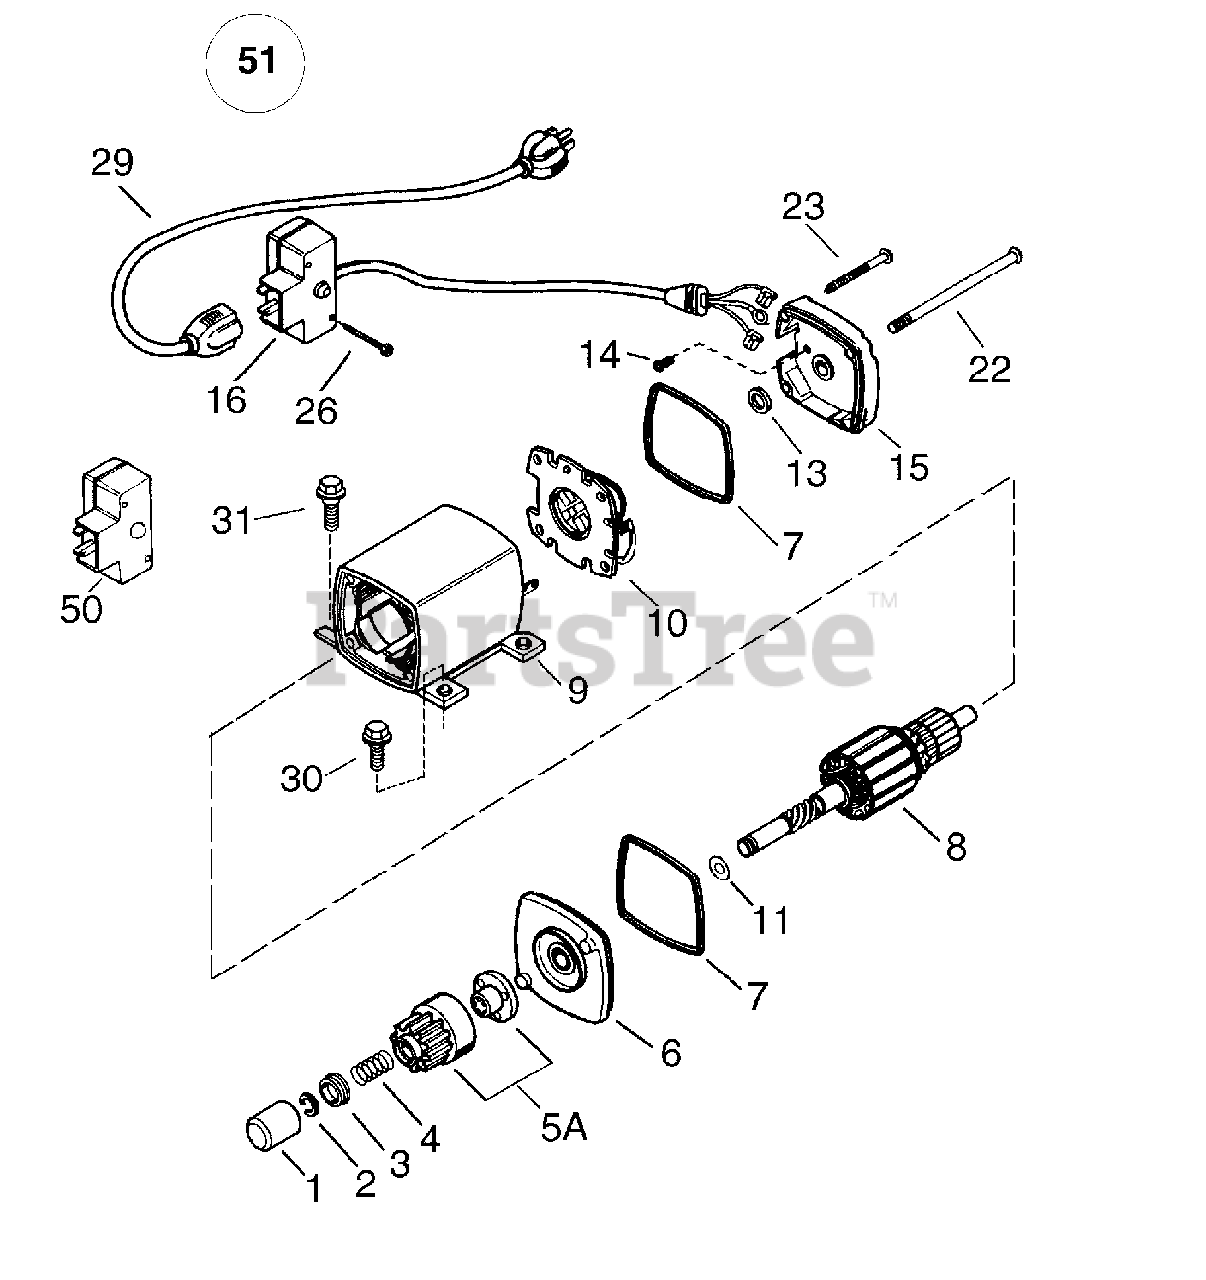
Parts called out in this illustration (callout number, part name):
1	Dust Cover
2	Retainer Ring
3	Spring Retainer
4	Anti-Drift Spring
5A	Nut & Gear
6	Drive End Cap Ass'y
9	Housing Ass'y
10	Brush Card Ass'y
11	Thrust Washer
13	Thrust Washer
14	Ground Screw
15	Commutator End Cap Ass'y
16	Switch Box Ass'y
22	Case Bolt
23	Grounding Screw
26	Screw, 6-32 x 2-1/2"
29	Extension Cord (10' 6")
30	Screw, Torx T-30, 1/4-20 x 1/2"
31	Screw, 1/4-20 x 1/2"
50	Switch Repair Kit
51	Electric Starter (110 Volt)
